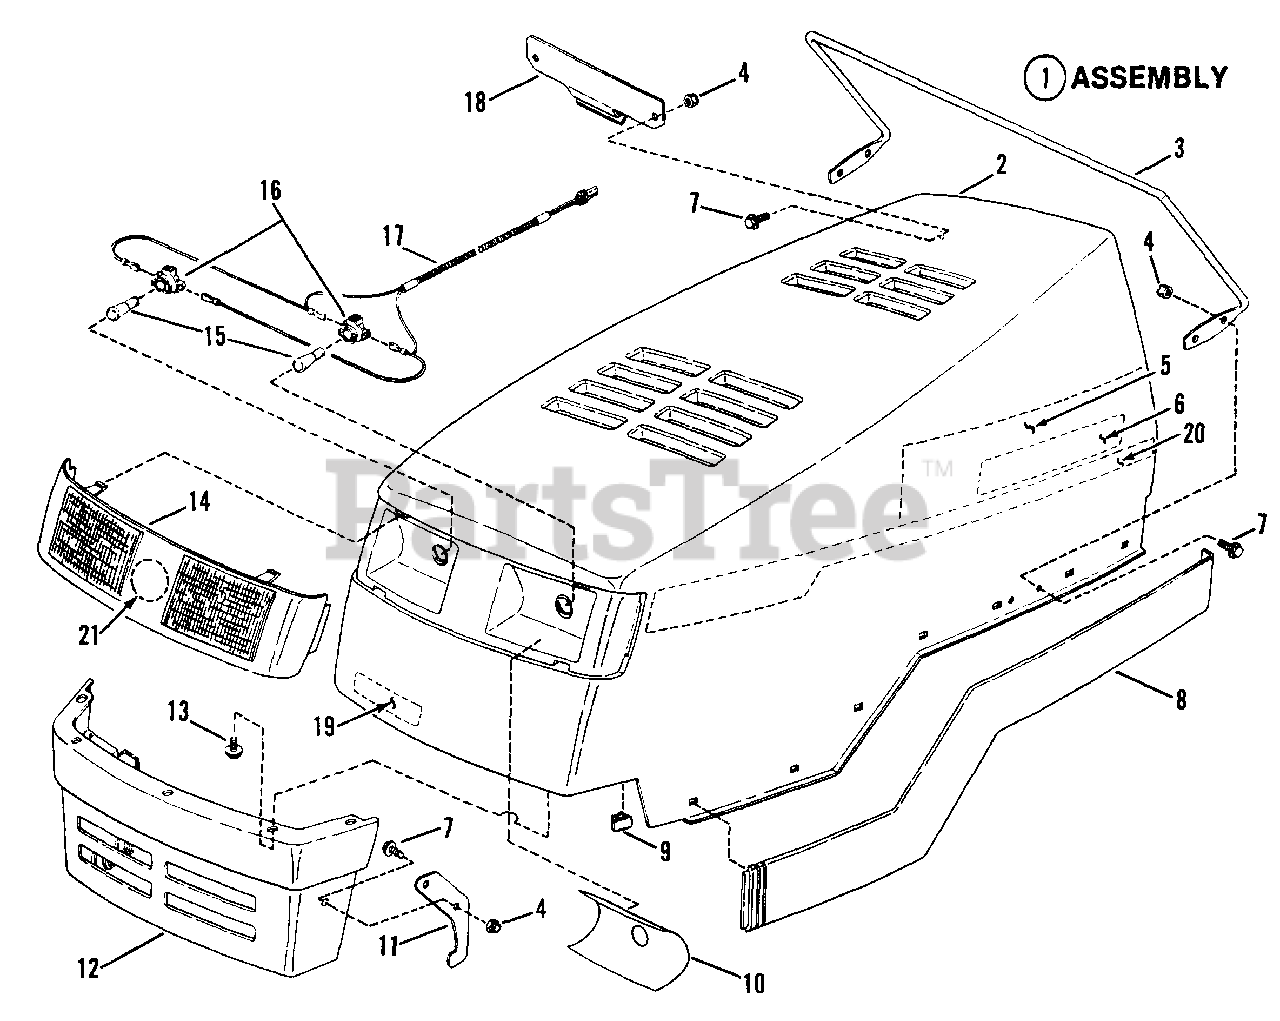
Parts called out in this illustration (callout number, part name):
1	KIT, Hood Assembly, Sloped Mozart
2	HOOD (No longer available, use kit 7063298)
3	ROD, Hood Latch
4	NUT, 1/4-20 Hex Lock
5	HEAT SHIELD, Hood 3" x 5" (No longer available)
6	DECAL-SNAPPER, Molded Logo (No longer available)
7	SCREW, 1/4-20 x 5/8" Torx, Truss Head
8	BUMPER (R.H.) (No longer available)
8	BUMPER (L.H. Shown) (No longer available)
9	CLIP, Wiring Harness .31"
10	DECAL, Reflect (R.H.)
10	DECAL, Reflect (L.H. Shown)
11	BRACKET, Latch Hook
12	BUMPER, Front (No longer available)
13	SCREW, #12 x 1/2"
14	LENS, Clear Bezel
15	BULB, Headlights, 1156
16	SOCKET, Headlight Bulb
17	HARNESS, Headlight Wiring
18	CLIP, Hood Latch
19	DECAL-SNAPPER, Molded Logo 4" - Blue (No longer available)
19	DECAL-SNAPPER, Molded Logo 4" - Green
20	DECAL, 1550LX - Blue (R.H.)(No longer available)
20	DECAL, 1550LX - Blue (L.H. Shown)(No longer available)
20	DECAL, 1550RX - Green (R.H.)
20	DECAL, 1550RX - Green (L.H. Shown)
21	DECAL, Convertible - Blue
21	DECAL, Twin-Turbo - Blue
21	DECAL, Recycling - Green (No longer available)
